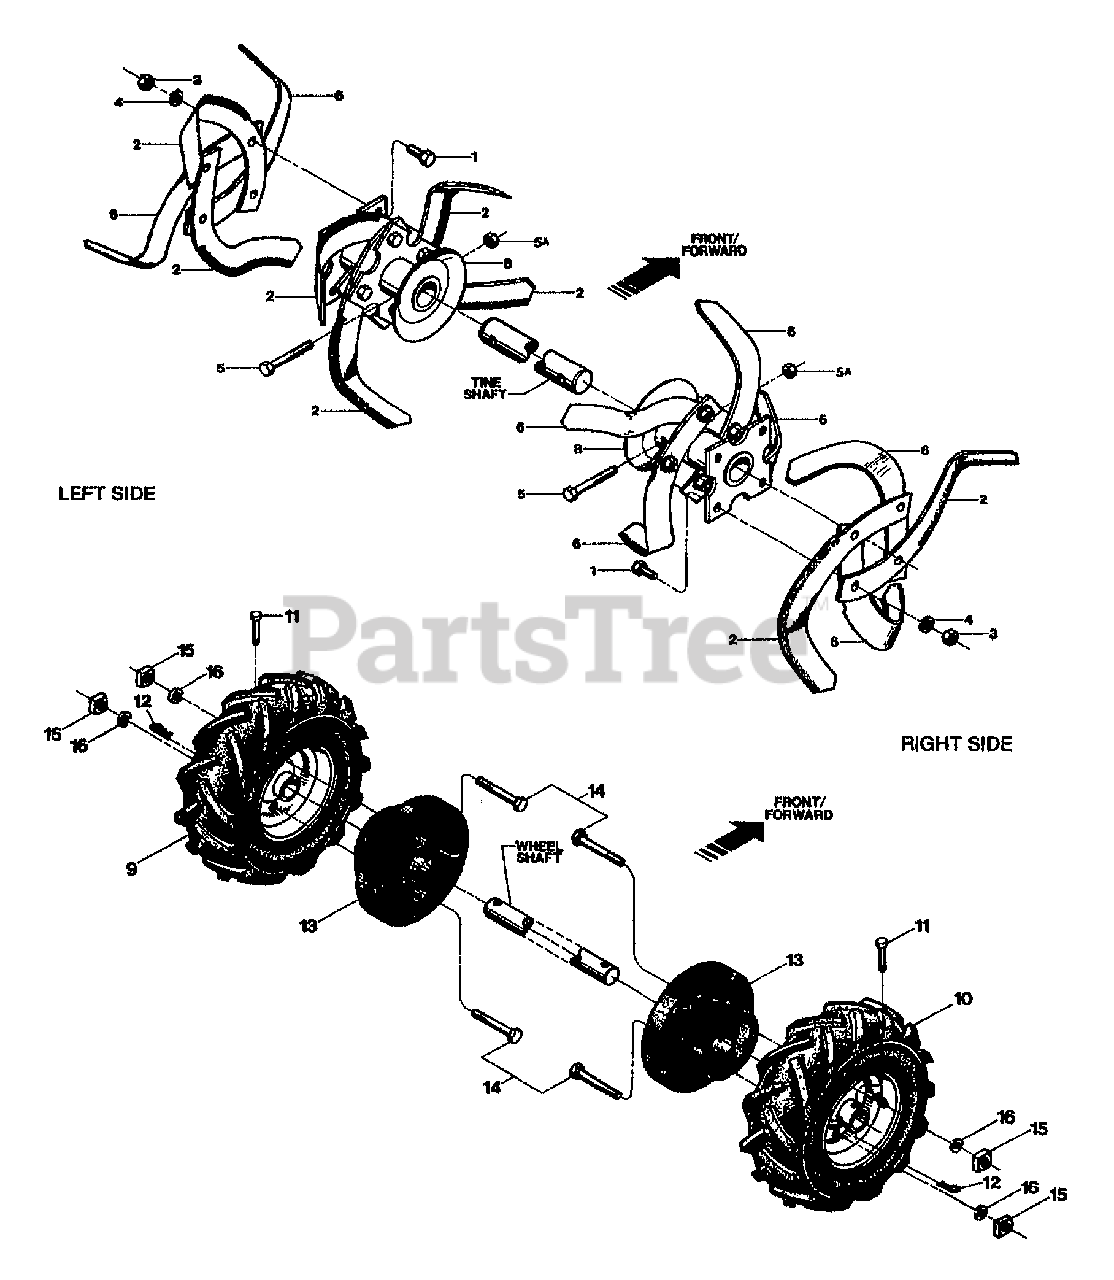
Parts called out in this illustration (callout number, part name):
1	SCR-HH 3/8-16X1.0 G5 ZP
2	TINE-BOLO RT W/HDW
3	NUT-HEX 3/8-16 ZP
4	WASHER-LK .375 @ DEPL
5	SCR-HH 3/8-16X2.00 G8 (HOLDER TO TILLER SHAFT)
5A	NUT-H/LK 3/8-16
6	TINE-BOLO LT W/HDW
8	WELD-TINE HOLDER ECONO (LEFT & RIGHT SIDES)
9	ASSM-WHEEL TIRE LT (15-20 LBS AIR REQ'D)
10	ASSM-WHEEL TIRE RT (15-20 LBS AIR REQ'D)
11	PIN-CLEVIS
12	PIN-CLIP .08
13	WEIGHT-WHEEL
14	SCR-HH 3/8-16X3.5 G5 ZP
15	NUT-SQ 3/8-16
16	WASHER-LK .375 @ DEPL
